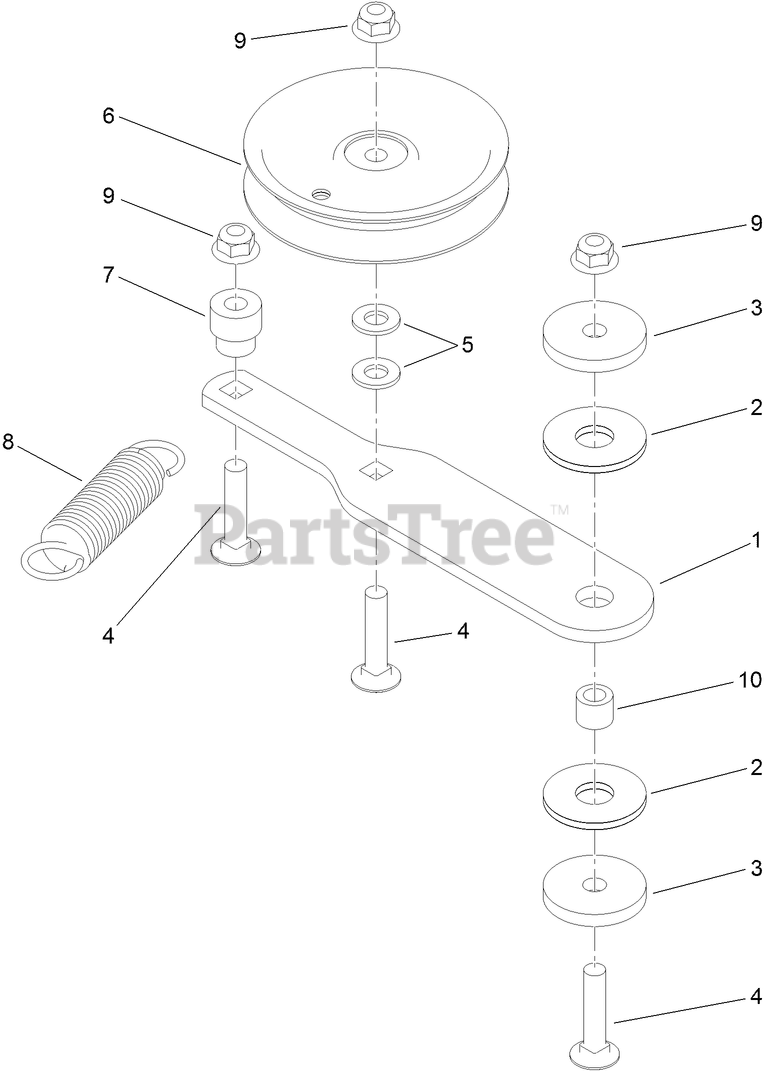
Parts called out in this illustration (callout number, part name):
1	ARM-IDLER
2	WASHER-FRICTION, COMPOSITE
3	WASHER-PLAIN
4	SCREW-CARR
5	WASHER-FLAT
6	PULLEY-IDLER
7	BUSHING-IDLER
8	SPRING-EXTENSION
9	NUT-HF, NI
10	BUSHING-LEVER, LIFT
